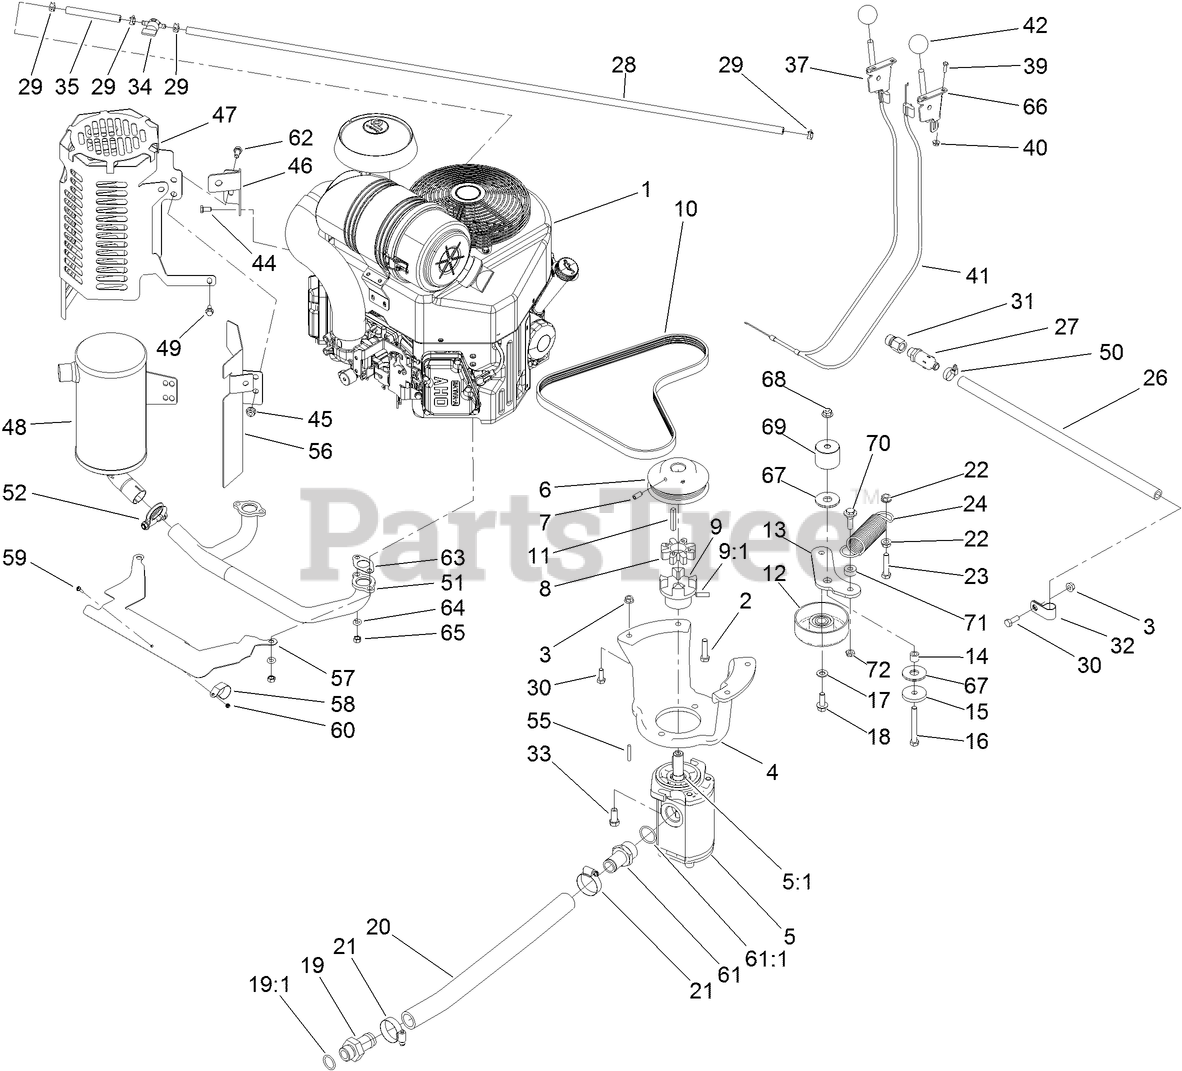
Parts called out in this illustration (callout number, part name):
1	ENGINE-KAWASAKI, FX730V
2	SCREW-HH
3	NUT-HF
4	MOUNT-PUMP
5	GEAR PUMP ASM
5:1	SEAL-WIPER
6	PULLEY-ENGINE
7	SCREW-SET, HSH
8	COUPLER-SPIDER
9	COUPLER-FLEX
9:1	SCREW-SET
10	BELT-V
11	KEY-SQUARE
12	PULLEY-IDLER
13	ARM-IDLER
14	BUSHING-LEVER, LIFT
15	WASHER-PLAIN
16	SCREW-HH
17	WASHER-FLAT
18	SCREW-HHF
19	FITTING
19:1	O-RING
20	HOSE-SUCTION
22	NUT-HHF, WHIZ
23	SCREW-HH
24	SPRING-EXTENSION
26	HOSE-VENT
27	VALVE-DRAIN, OIL
28	HOSE-FUEL
29	CLAMP-HOSE
30	SCREW-HH
31	Adapter
32	CLAMP-R
33	SCREW-HH
34	VALVE-FUEL
35	HOSE-FUEL
37	LEVER-CONTROL
40	NUT-LOCK, FLANGE
41	CABLE-CONTROL
44	SCREW-HH
45	NUT-HF
46	BRACKET-MOUNT, MUFFLER
47	SHIELD-MUFFLER
48	MUFFLER
49	SCREW-HHF
50	CLAMP-HOSE
51	MANIFOLD
52	CLAMP-MUFFLER
55	KEY-SQUARE
56	BRACKET-SHIELD, HEAT
57	PLATE-SHIELD, HEAT
59	SCREW-PAN
60	NUT-HEX
61	FITTING-STR
61:1	O-RING
62	SCREW-HH
63	GASKET-EXHAUST
64	WASHER-SPRING
65	NUT-HEX
66	LEVER-CONTROL
67	WASHER-FRICTION, COMPOSITE
68	NUT-HF, NI
69	SPACER-IDLER
70	SCREW-SHOULDER, HWH
71	SPACER
72	NUT-LOCK, NI
